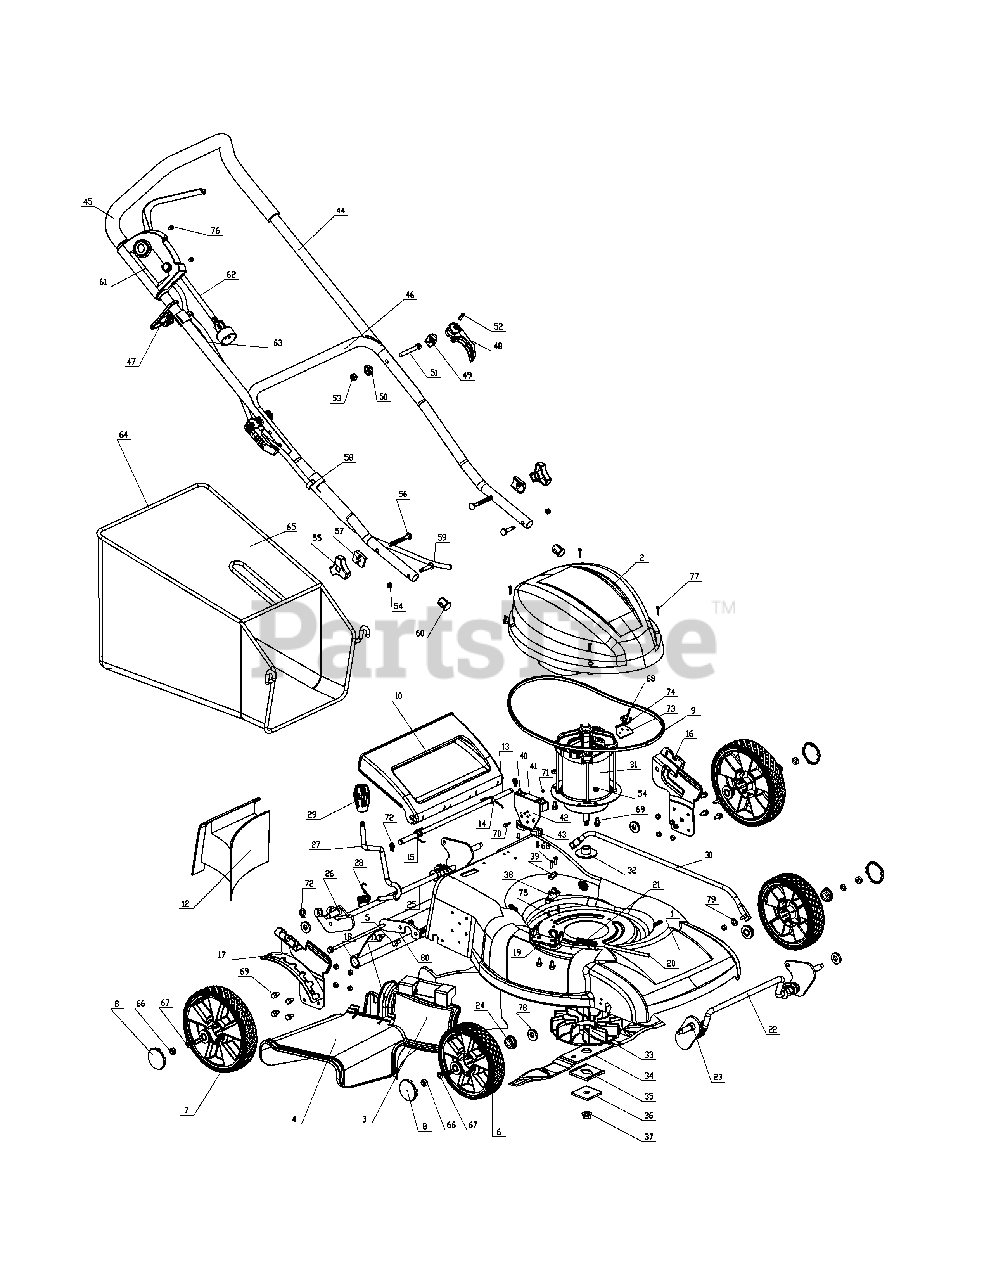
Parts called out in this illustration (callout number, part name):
2	Shroud
3	Mulch Door
4	Discharge Chute
5	Trail Shield
6	Front Wheel
7	Rear Wheel
8	Wheel Cap
9	Shroud Seal
10	Rear Door
11	Rear Baffle
12	Mulch Plug
14	Spring
15	Spring
16	Left Bracket
17	Right Bracket
18	Trailshield Rod
19	Mulch Door Bracket
20	Mulch Door Rod
21	Mulch Door Spring
22	Front Shaft Assembly
23	Spacer Bushing
24	Wheel Bushing
25	Rear Shaft Assembly
26	Spacer Bushing
27	Height Adjust Handle
28	Height Adjust Spring
29	Height Adjust Knob
30	Height Adjust Rod
31	Motor
32	Flange
33	Electric Motor Fan
34	Blade
35	Washer
36	Washer
38	Strain Relief Bracket
39	Strain Relief Cap
40	Resistor
41	Resistor Holder
42	Resistor Bracket
43	Resistor Base
44	Upper Handle
45	Handle Grip
46	Lower Handle
47	Cord Retainer
48	Quick Release Handle
49	Washer
50	Quick Release Knob
51	Quick Release Pin
54	Nylock Nut
55	Wing Knob
56	Screw, M8
57	Washer
58	Cord Clip
59	Shoulder Bolt
61	Switch Box Assembly
62	AC Power Cord
63	Motor Cord
64	Grassbag Frame
65	Grassbag
66	Lock Nut
67	Washer
68	Screw, St, M4.8 x 16
70	Screw, M5x12
71	Nut, Lock, M4
72	Ring, Snap, 10mm
73	Base, Electric-Bridge
74	Electric, Bridge
75	Screw, St, M4.8 x 16
76	Screw, St, M4.8 x 16
77	Screw, M5x12
78	Washer, Spring
79	Pin, Cotter
80	Bracket, Wheel
